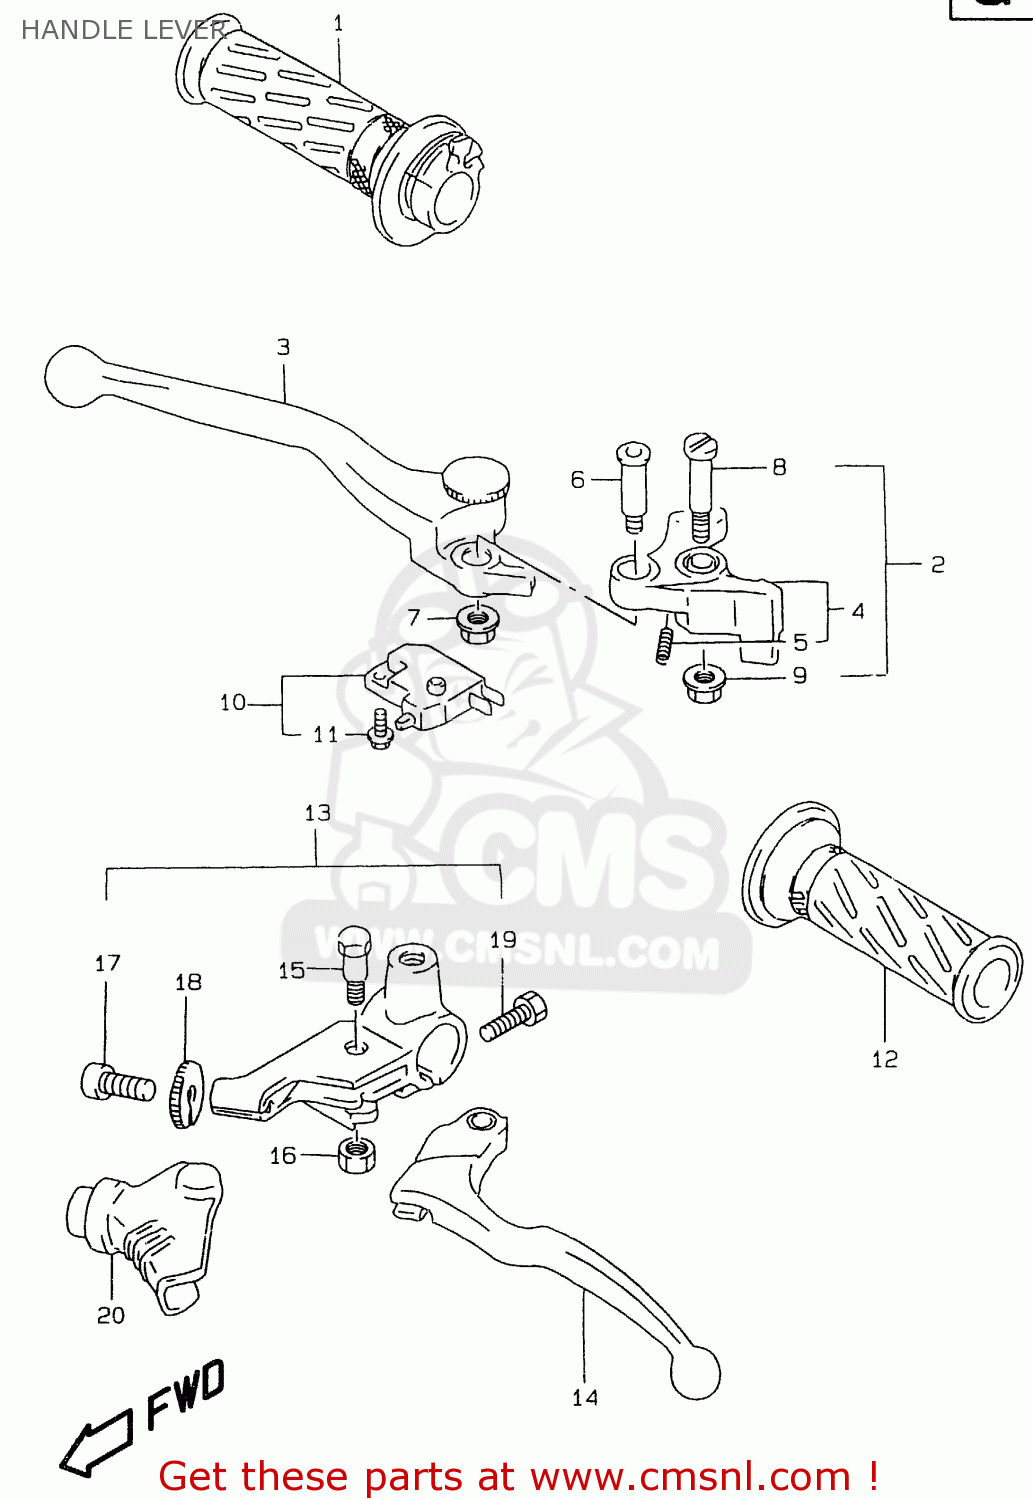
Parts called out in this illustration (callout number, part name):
1	GRIP,THROTTLE
2	LEVER ASSY,BRAKE
3	LEVER,ADJUST
4	KNOCKER
5	SPRING
6	BOLT,LEVER
7	NUT
8	BOLT,LEVER PIVOT
9	NUT
10	SWITCH ASSEMBLY,STOP
11	SCREW
12	GRIP,LEFT
13	LEVER ASSY,CLUTCH
14	LEVER,CLUTCH
15	BOLT,LEVER SET
16	NUT
17	ADJUSTER,CABLE
18	NUT,CABLE ADJUSTER
19	SCREW
20	COVER,CLUTCH LEVER
